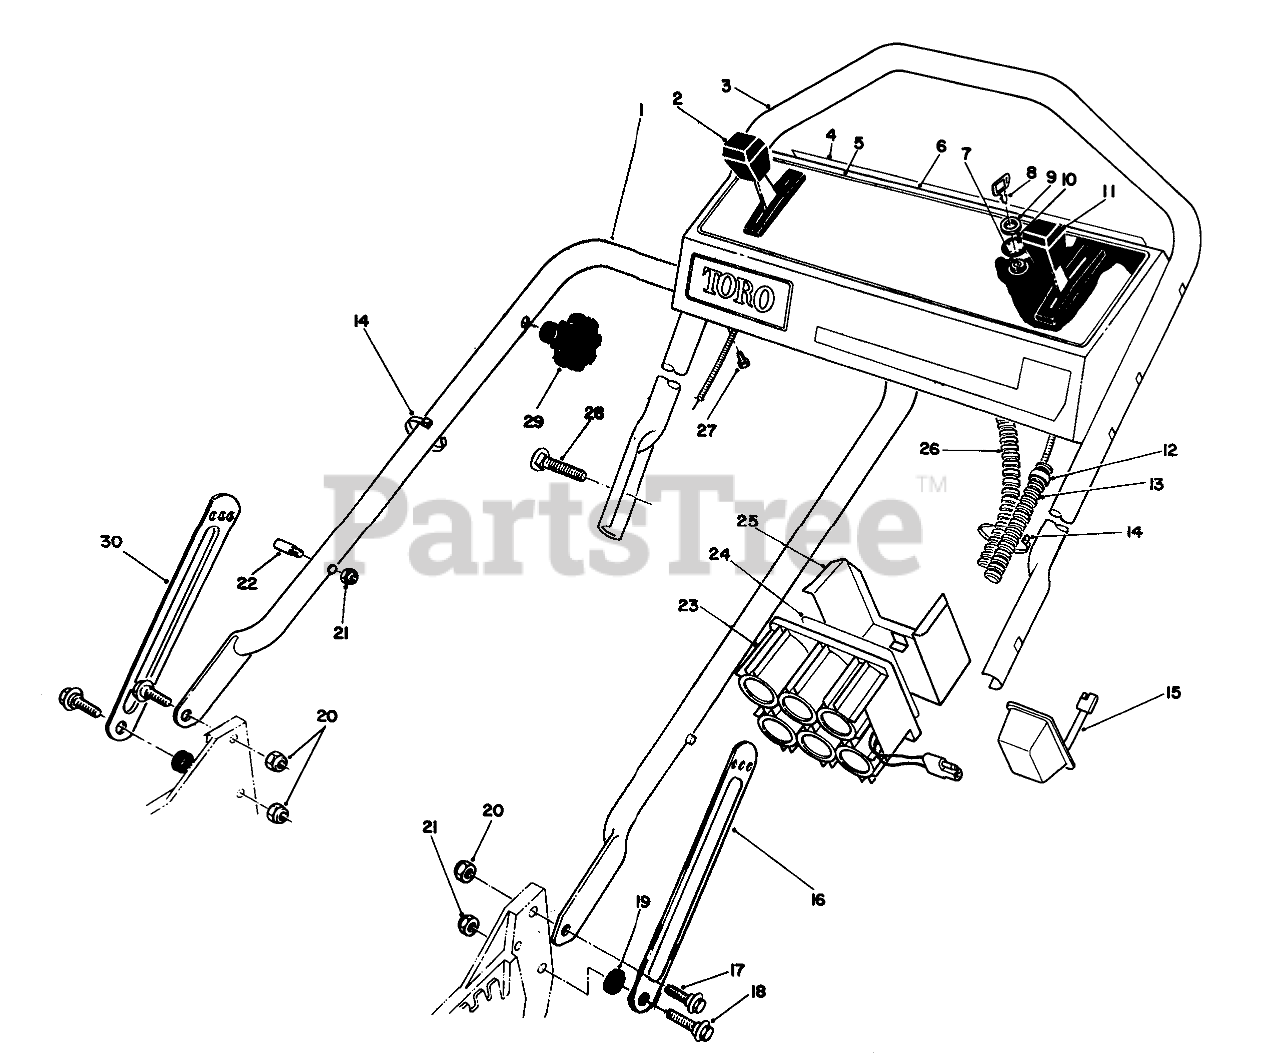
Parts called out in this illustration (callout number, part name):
1	LOWER HANDLE ASM
2	Control-Ground Speed
3	UPPER HANDLE
4	DECAL-PANEL, DANGER
5	DECAL - INSTRUCTIONS
6	Panel-Control (Incl. Ref. #4 & 5)
7	STARTER SWITCH ASM
8	KEY-IGNITION
9	NUT-HH
10	WASHER-TOOTH, INTERNAL
11	THROTTLE CONTROL
12	FITTING-RING
13	CONTROL CABLE COVER
14	TIE-CABLE
15	Charger
16	LH HANDLE LATCH
17	SCREW-SHOULDER
18	SCREW-SHOULDER
19	SPACER
20	NUT-LOCK, NI
21	NUT-LOCK, NI
22	HANDLE PIN
23	BATTERY ASSEMBLY
24	Decal
25	Retainer-Battery
26	Harness-Wire
27	SCREW-HWHTF
28	5/16-18 X 2 HNDLE SCREW
30	RH HANDLE LATCH
